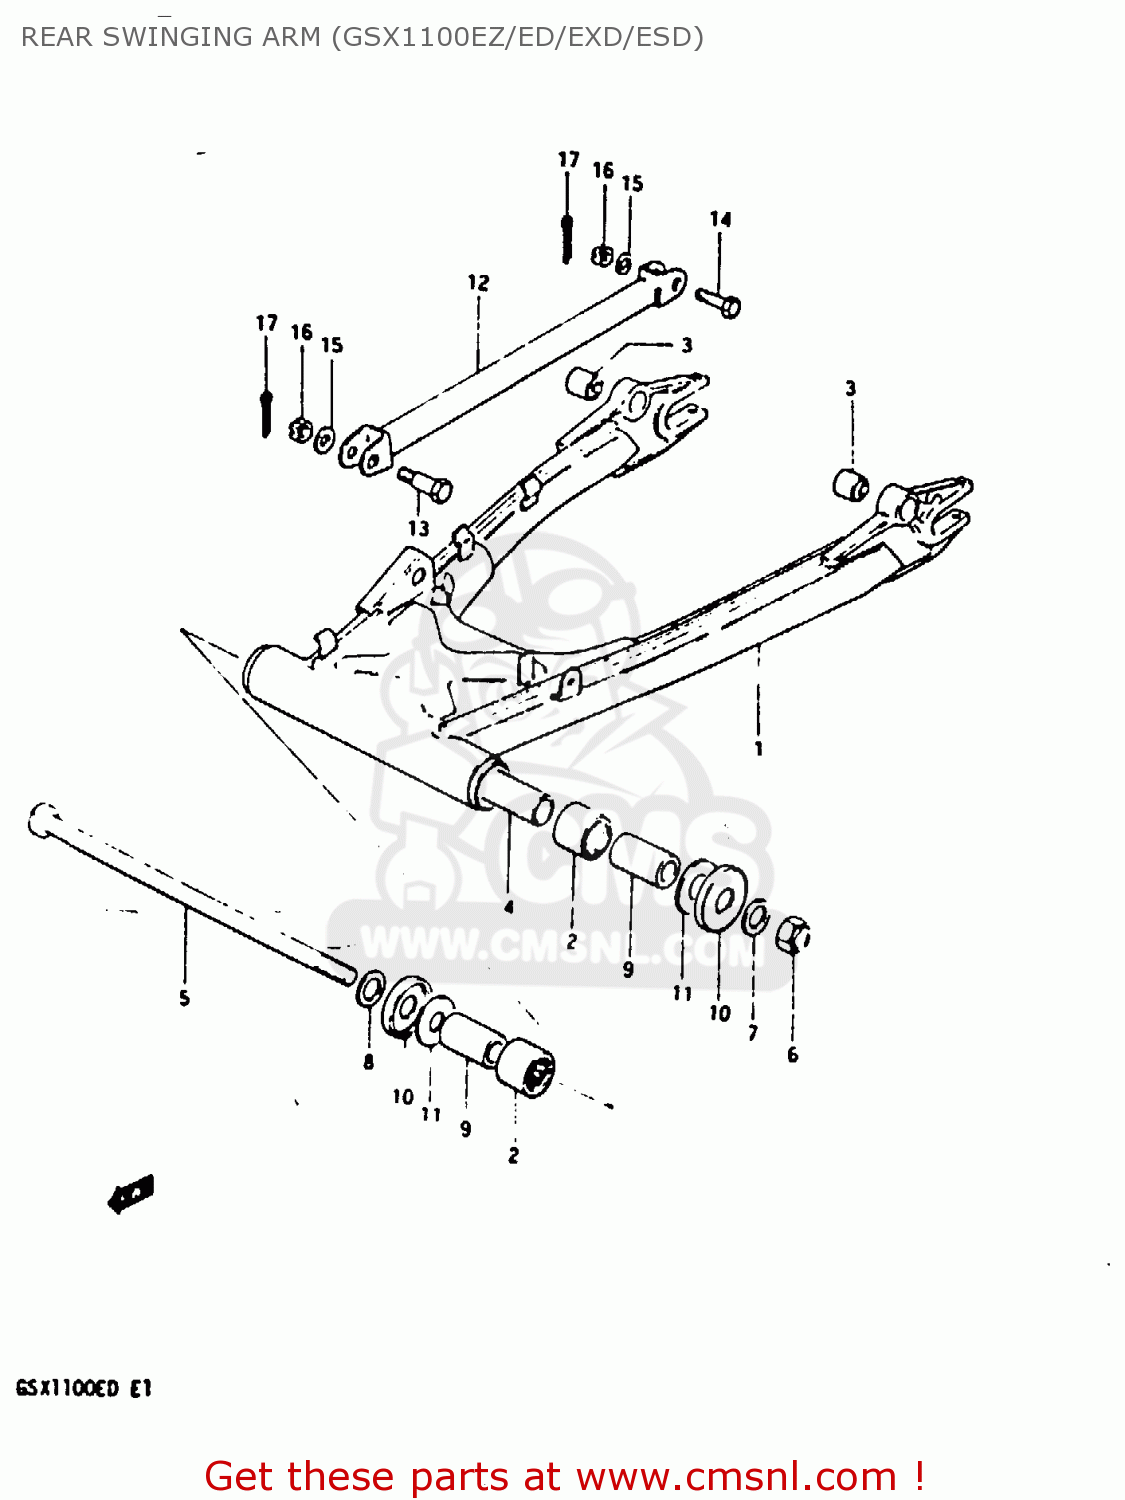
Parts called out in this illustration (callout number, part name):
1	SWING ARM ASSEMBLY,REAR
2	BEARING(25X33X30)
3	BUSH
4	SPACER,RR SWGARM PIVOT CTR
5	SHAFT,REAR SWING ARM
6	NUT 16MM
7	WASHER
8	WASHER
9	SPACER,RR SWGARM PIVOT
10	COVER,RR SWINGINGARM PIVOT
11	WASHER
12	LINK,RR TORQUE
13	BOLT
14	BOLT(10X39)
15	WASHER
16	NUT
17	PIN 20X20
